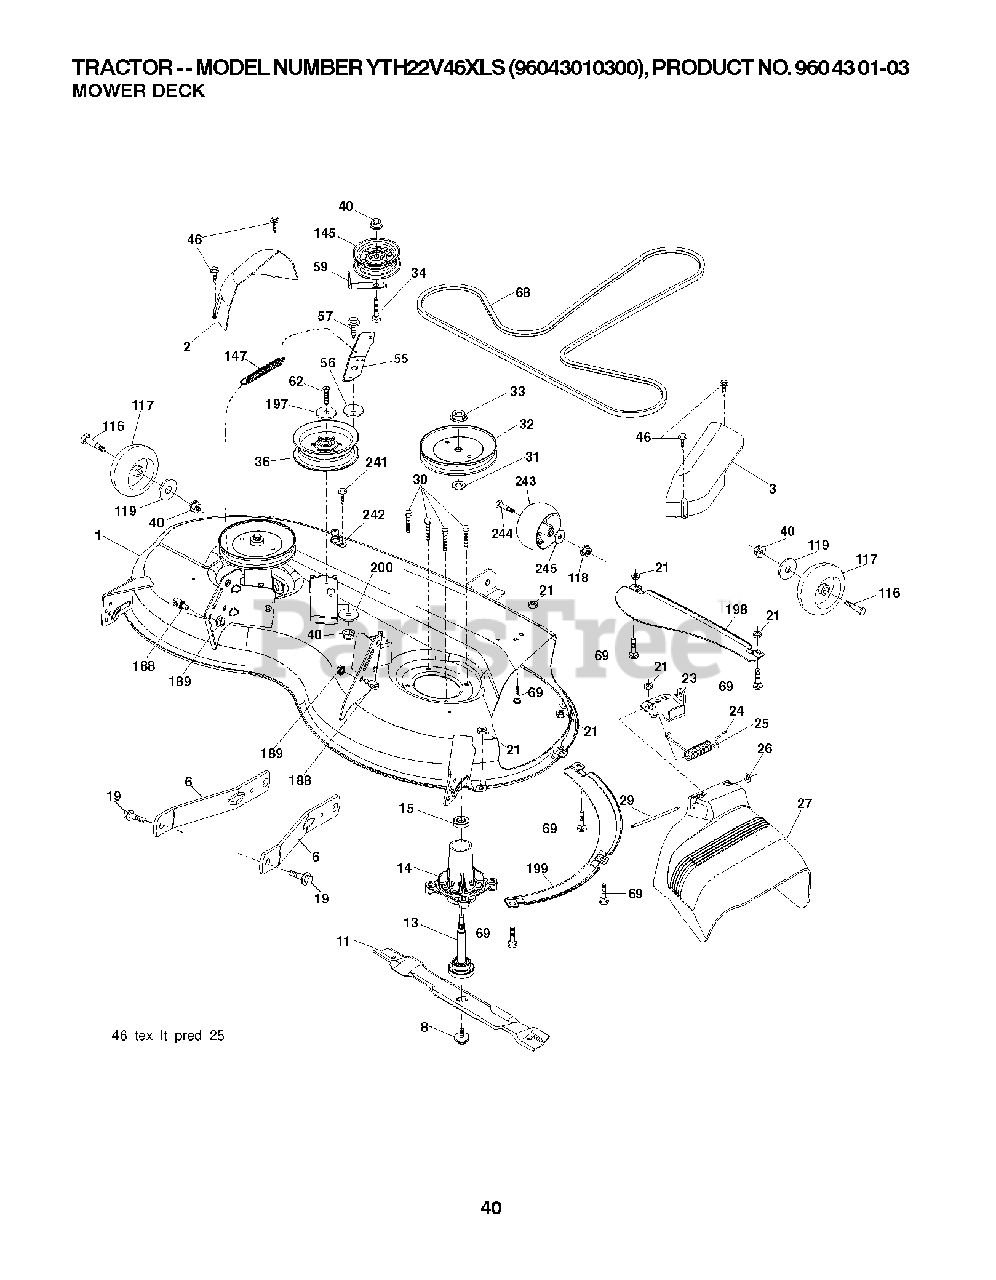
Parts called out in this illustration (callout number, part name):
1	MOWER HOUSING
2	COVER.MANDREL.LH.46"
3	COVER.MANDREL.RH.46"
6	ARM.SUSPENSION.MOWER.R
8	BOLT.WASHER.ASM.7/16-2
11	BLADE.MOWER.46".HI.LIFT
13	SHAFT.ASM.MDRL.N/GREASE.38
14	HOUSING.MANDREL.4PT.
19	BOLT.SHOULDER
21	LOCKNUT
23	BRKT.DEFLECTOR.38"2005+
24	CAP-SLEEVE LT
25	SPRING.TORSION.DEFLECT
26	NUT PUSH M
27	SHIELD.DEFLECTOR.MOWER.46"BLAC
29	ROD.HINGE
30	SCREW, WASHER HEAD
31	WASHER.SPACER.MANDREL
32	PULLEY.MANDREL.5.438.PD
33	NUT.FLANGE.LOCK.TOP
34	BOLT.3/8-16X1.50
36	PULLEY.IDLER.2006
40	NUT LOCK FLG 3/8-16 UNC
46	SCREW.1/4-20X5/8
56	SPACER.RETAINER
57	SCREW 3/8-16X1
59	GUARD, BELT
62	BOLT-HEX EAK
68	V-BELT
69	BOLT
116	BOLT.SHOULDER.3/8-16X3-5/8.
117	WHEEL. GUAGE RALLY
118	LOCKNUT
119	WASHER
145	PULLEY.IDLER.48"PRIMARY
147	SPRING.MOWER.DRIVE.ELECTRIC
188	STUD.FASTNER.W/ANTI-ROTATE
189	NUT LOCK HEX FLANGE 5/16-18
197	WASHER
198	BAFFLE CENTER FRONT
199	BAFFLE FRONT RH
200	WASHER.13/32 X 1 X 1/2.11GUARD
241	SCREW.TT.#10-32X.5.3/8.FLANGE
242	PORT.WASHOUT
243	WHEEL.GAGE.HALF.SPOKED
244	BOLT M
245	WASHER
245	COUPLING.QUICK CONNECT
245	RB MANDREL.ASM.SUB-NON.GR
245	DECK.ASM SVC 46"HP E 5GW WP668
